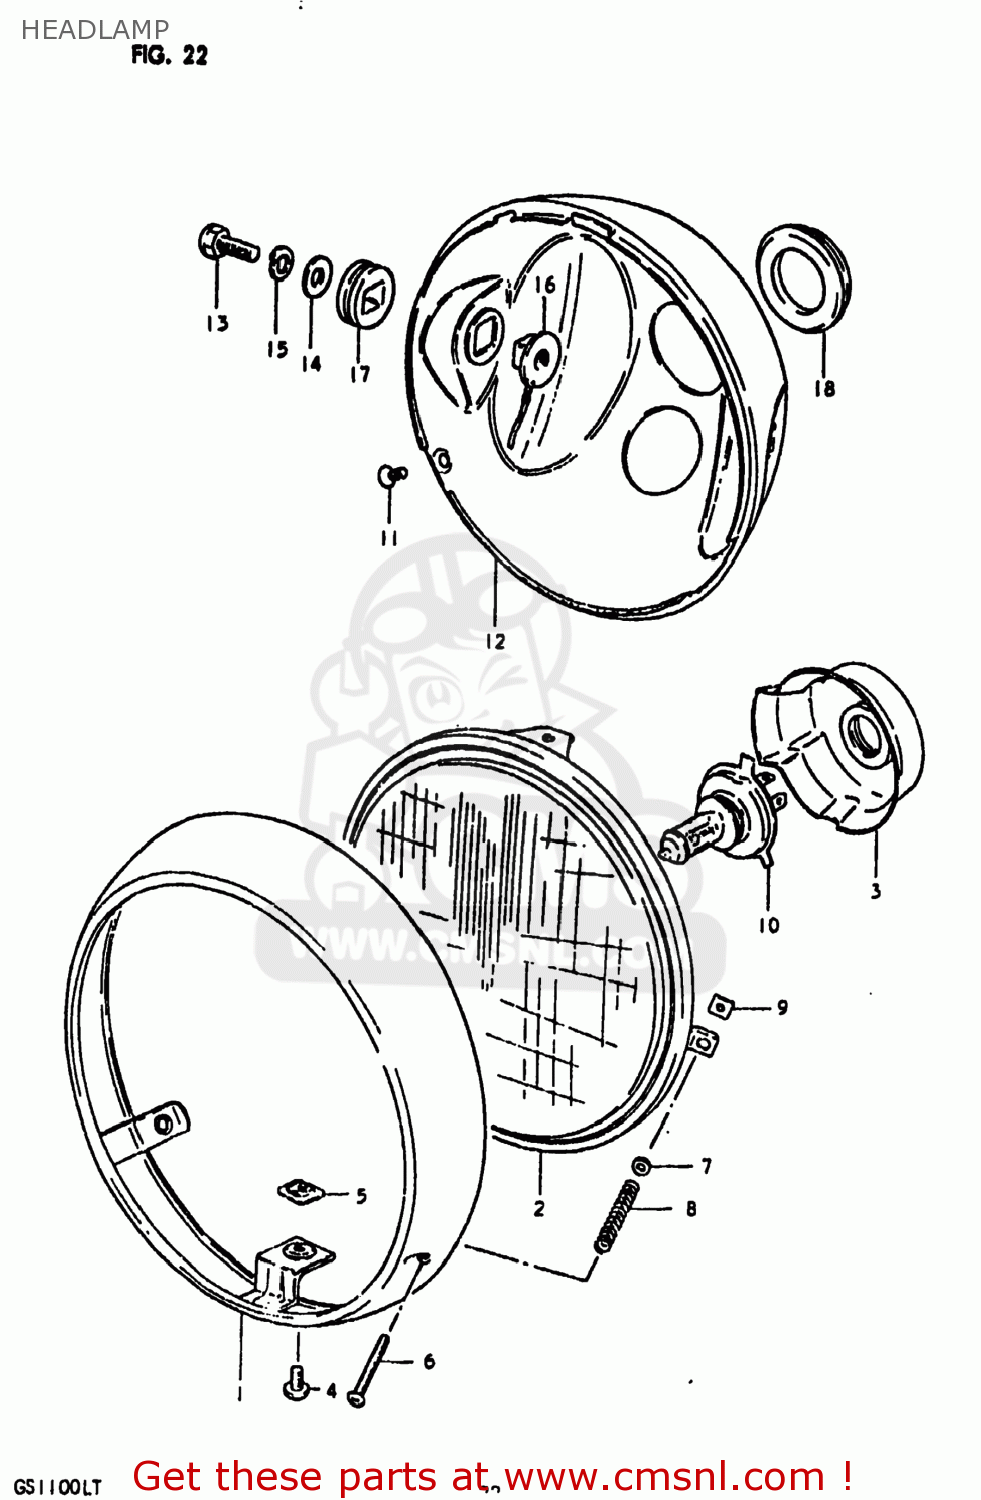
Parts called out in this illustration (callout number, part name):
1	RIM,HEADLAMP
2	LAMP UNIT
3	COVER,HEADLAMP SOCKET
4	SCREW
5	NUT
6	SCREW,HEADLAMP ADJUST
7	WASHER
8	SPRING,HEADLAMP ADJUST
9	NUT,HEADLAMP ADJUSTER
10	BULB(12V60/55W,H4)
11	SCREW
12	HOUSING,HEADLAMP
13	BOLT
14	WASHER
15	LOCK WASHER
16	SPACER,HEADLAMP HOUSING
17	CUSHION,HEADLAMP HOUSING
18	GROMMET,HEADLAMP HOUSING
